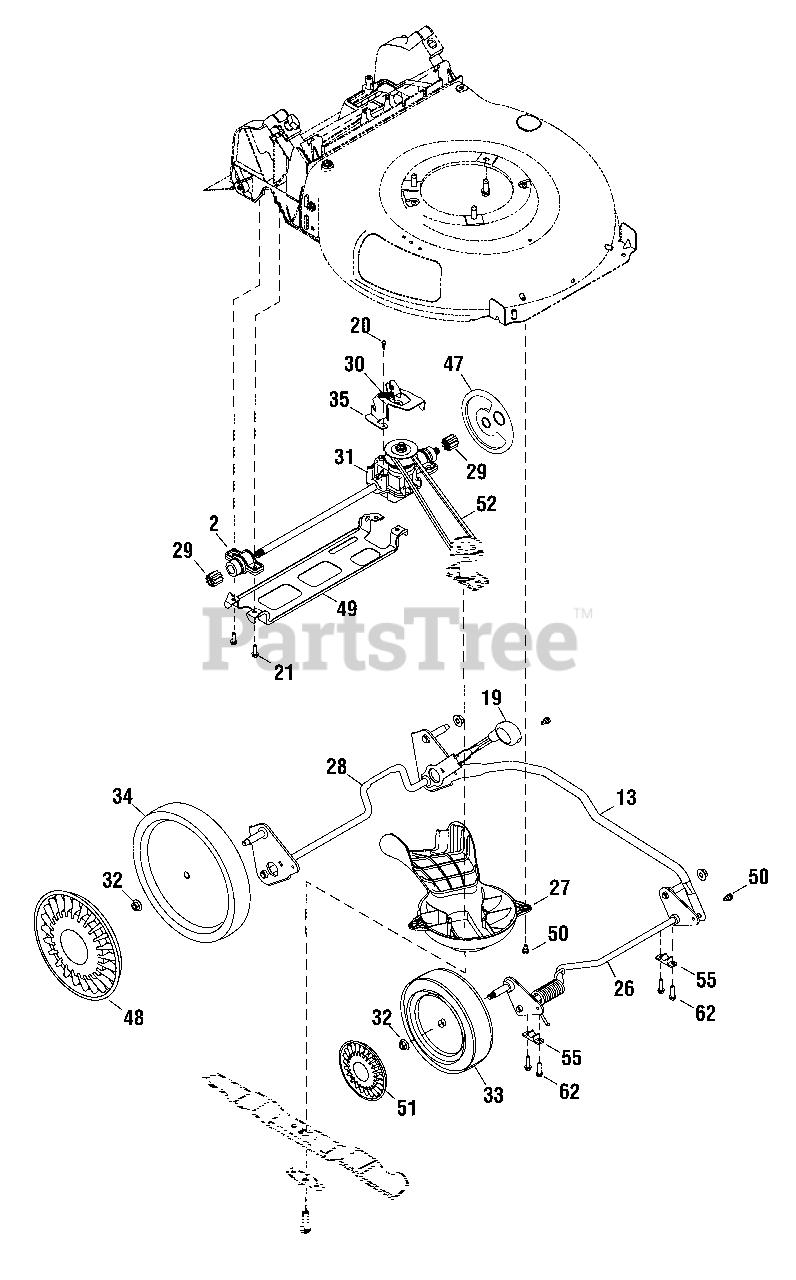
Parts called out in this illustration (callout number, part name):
2	BEARING
13	CROSS BRACKET
19	KNOB, Adjustment Lever
20	SCREW, Hex Washer Head, .159 x .43
21	SCREW, 1/4-15 x 1-1/4
26	AXLE ASSEMBLY, Front
27	BAFFLE, Engine
28	AXLE ASSEMBLY, Rear
29	GEAR, 9T
30	SPRING, Extension, 2.405
31	TRANSMISSION
32	NUT, Hex Flange, Nylock, 3/8-16
33	WHEEL, Front
34	WHEEL, Rear
35	BRACKET, Transmission
47	COVER, Wheel, Dust
48	HUBCAP, 11", Silver
49	BRACKET, Rear Support
50	BOLT, Shoulder, 1/4-20
51	HUBCAP, 8" Silver
52	V-BELT, 3L, 31.25"
55	BUSHING, Lock
62	SCREW, 1/4-15 x 1
